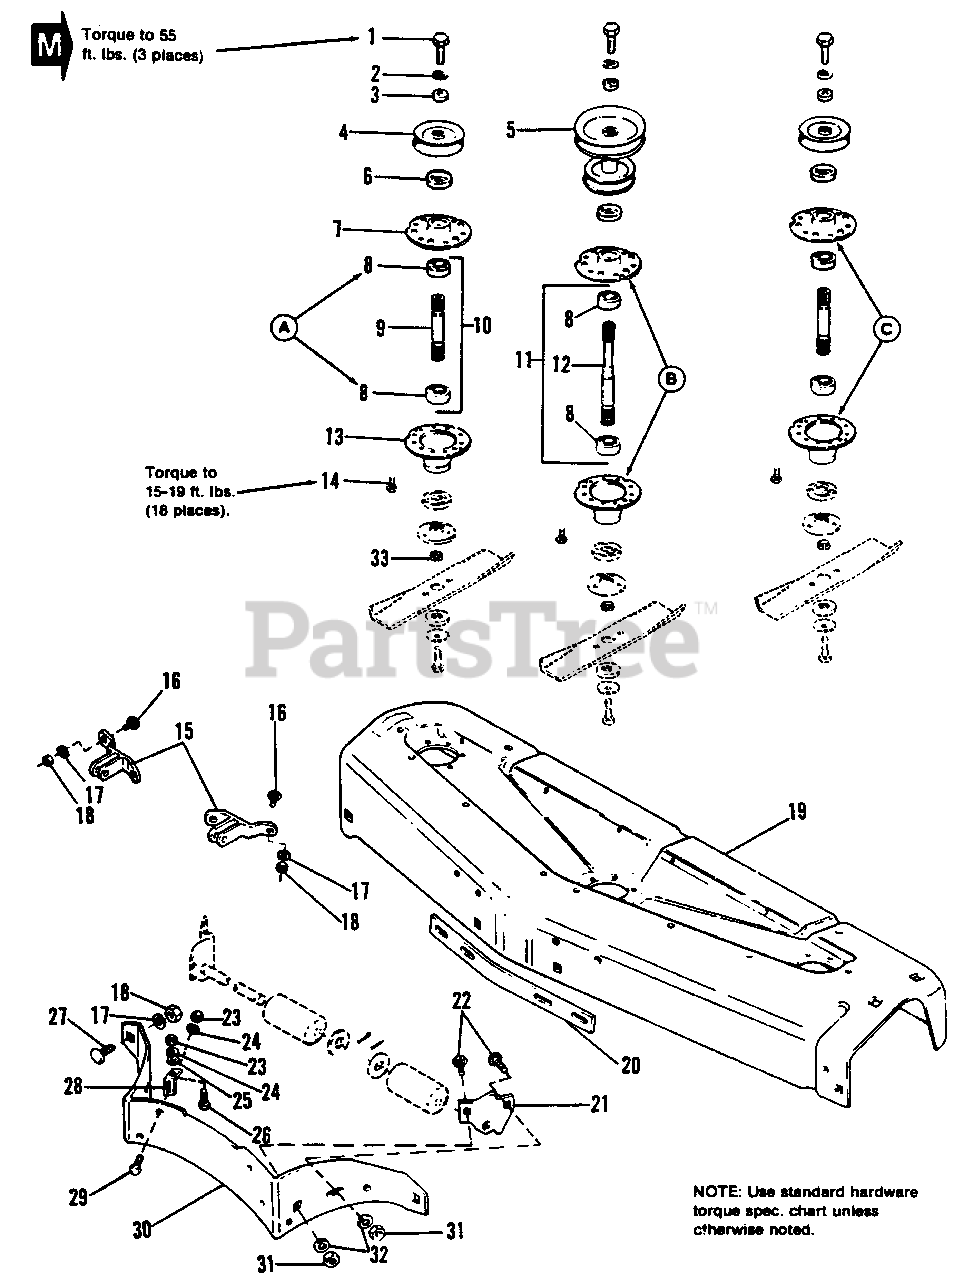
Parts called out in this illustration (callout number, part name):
1	CAPSCREW, Hex Hd., 7/16-14 x 1-1/4
2	LOCKWASHER, 7/16
3	WASHER, Plain, 29/64
4	PULLEY ASSY., Deck Drive
5	PULLEY ASSY.
6	SHIELD, Bearing Upper, Arbor
7	HOUSING, Top
9	SHAFT, Arbor (Includes Ref. No. 33)
10	SHAFT & BEARING ASSY., Side (Includes Ref. No. 8, 9 & 33)
11	SHAFT & BEARING ASSY., Center (Includes Ref. Nos. 8, 12 & 33)
12	SHAFT, Arbor, Center (Includes Ref. No. 33)
13	HOUSING, Bottom
14	SCREW, Hex Wash. Hd., Taptite, 5/16-18 x 3/4
15	BRACKET ASSY., Front
16	CARRIAGE BOLT, 3/8-16 x 1-1/4
17	LOCKWASHER, 3/8
18	NUT, Hex, Full, 3/8-16
19	HOUSING, 48"
20	BAR, Reinforcement
21	BRACKET, Roller, L.H.
22	CARRIAGE BOLT, 5/16-18 x 3/4
23	NUT, Hex, Full, 1/4-20
24	LOCKWASHER, 1/4
25	WASHER, Plain, 1/4
26	SCREW, Thd. Forming, 1/4-20 x 3/4
27	CARRIAGE BOLT, 3/8-16 x 3/4
28	CLIP, Baffle
29	CAPSCREW, Hex Hd., 1/4-20 x 5/8
31	NUT, Hex, Full, 5/16-18
32	LOCKWASHER, 5/16
33	COLLAR, Mower Arbor
